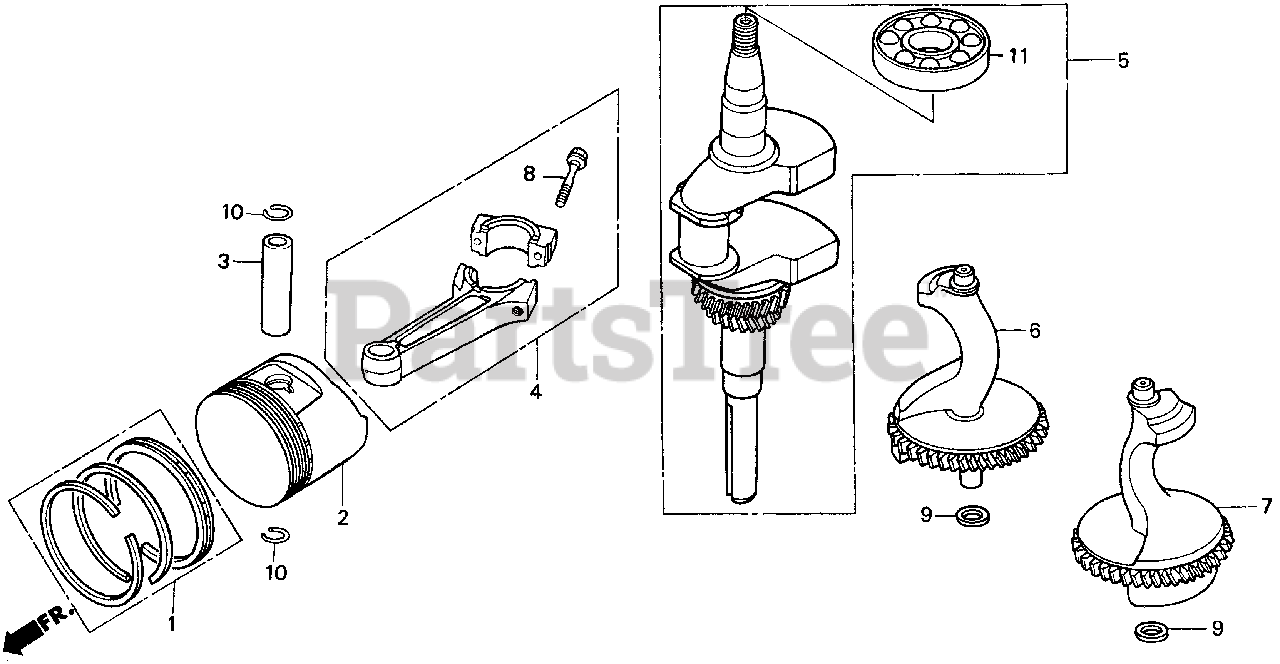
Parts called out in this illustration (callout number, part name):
1	RING SET, PISTON (STD)
1	RING SET, PISTON (OS 0.25)
1	RING SET, PISTON (OS 0.50)
1	RING SET, PISTON (0.75)
2	PISTON (STD)
2	PISTON (OS 0.25)
2	PISTON (OS 0.50)
2	PISTON (0.75)
3	PIN, PISTON
4	ROD ASSY., CONNECTING
4	ROD ASSY., CONNECTING (US 0.25)
5	CRANKSHAFT
6	WEIGHT A, BALANCER
7	WEIGHT B, BALANCER
8	BOLT, CONNECTING ROD
9	WASHER, THRUST (14MM)
10	CLIP, PISTON PIN (20MM)
